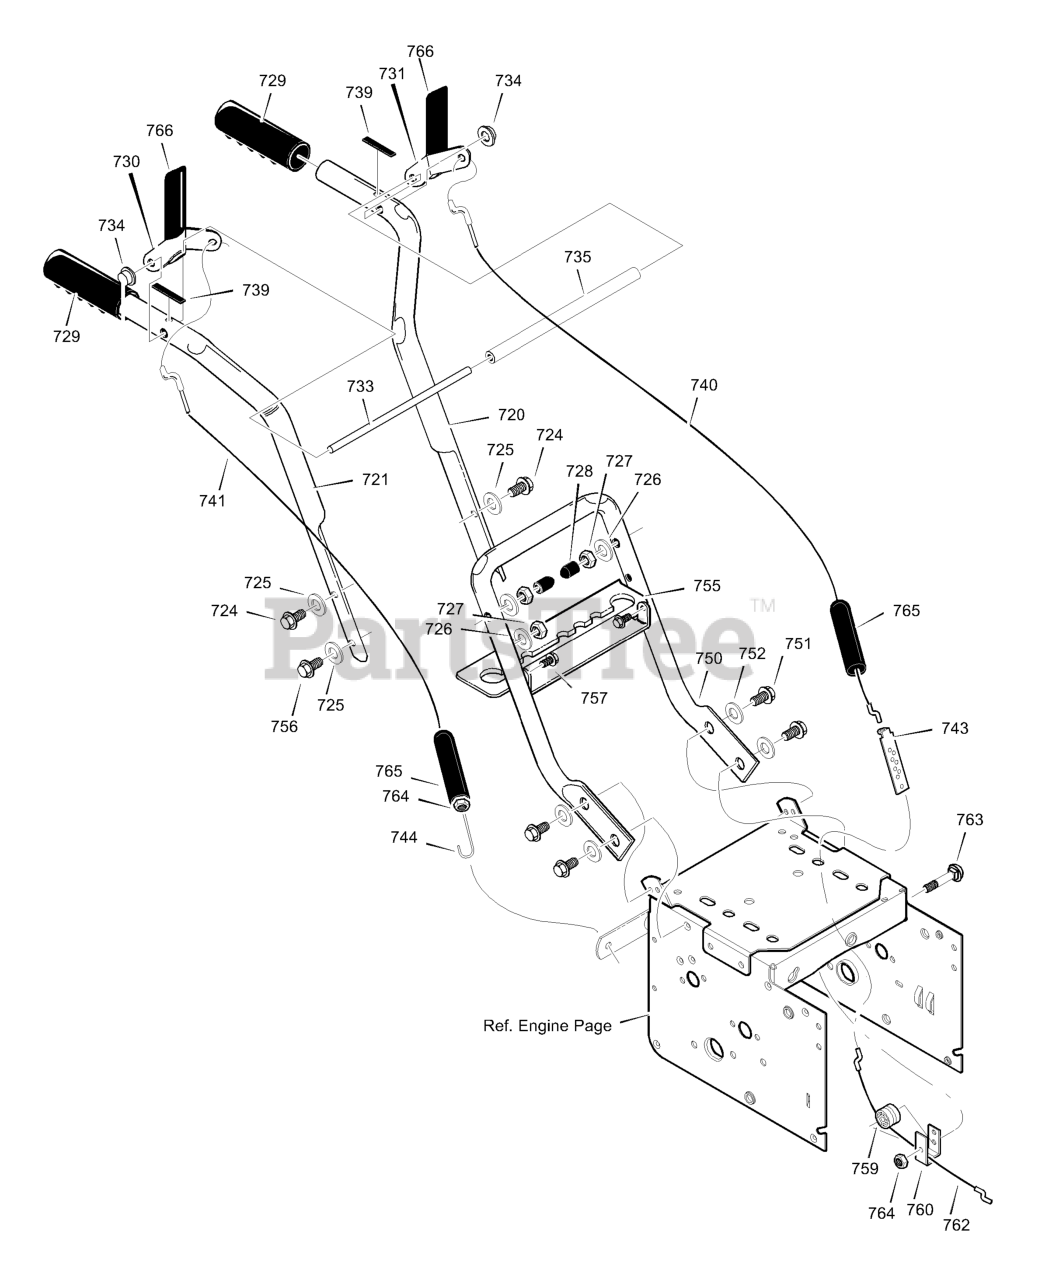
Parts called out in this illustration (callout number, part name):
720	HANDLE, UPPER LH
721	HANDLE, UPPER RH
724	SCREW, 5/16-18 x 2.75
725	WASHER, FLAT
726	WASHER, SPTLK .31X.58X.08
727	NUT, 5/16-18 REGHEX
728	STOP, RED PLASTIC
729	GRIP-HANDLE FINGER
730	LEVER, ASSY CLUTCH DRIVE RH
731	LEVER, ASSY CLUTCH DRIVE LH
733	ROD, PIVOT CLUTCH
734	NUT, PUSH ON CAP
735	SPACER-HANDLE
739	BUMPER, RECTANGLE
740	CABLE, CLUTCH 28.44L
741	CABLE, AUGER CLUTCH
743	BRACKET, CABLE ADJUSTER
744	SPRING, AUGER CLUTCH
745	NUT, 1/4-20
750	HANDLE, LOWER
751	SCREW, TAP 5/16-18 X .75
752	WASHER, SPTLK
755	BRKT, GEAR SELECTOR
756	SCREW, 5/16-18 x 2.00
757	SCREW, 1/4-20 X 0.63
759	SPOOL-CABLE, AUGER CLUTCH
760	BRACKET, CABLE SPOOL YZ
762	CABLE, LOWER DRIVE 12"
763	BOLT, HEX 1/4-20 X 1.50 YZ
764	NUT
765	BOOT, CLUTCH SPRING
